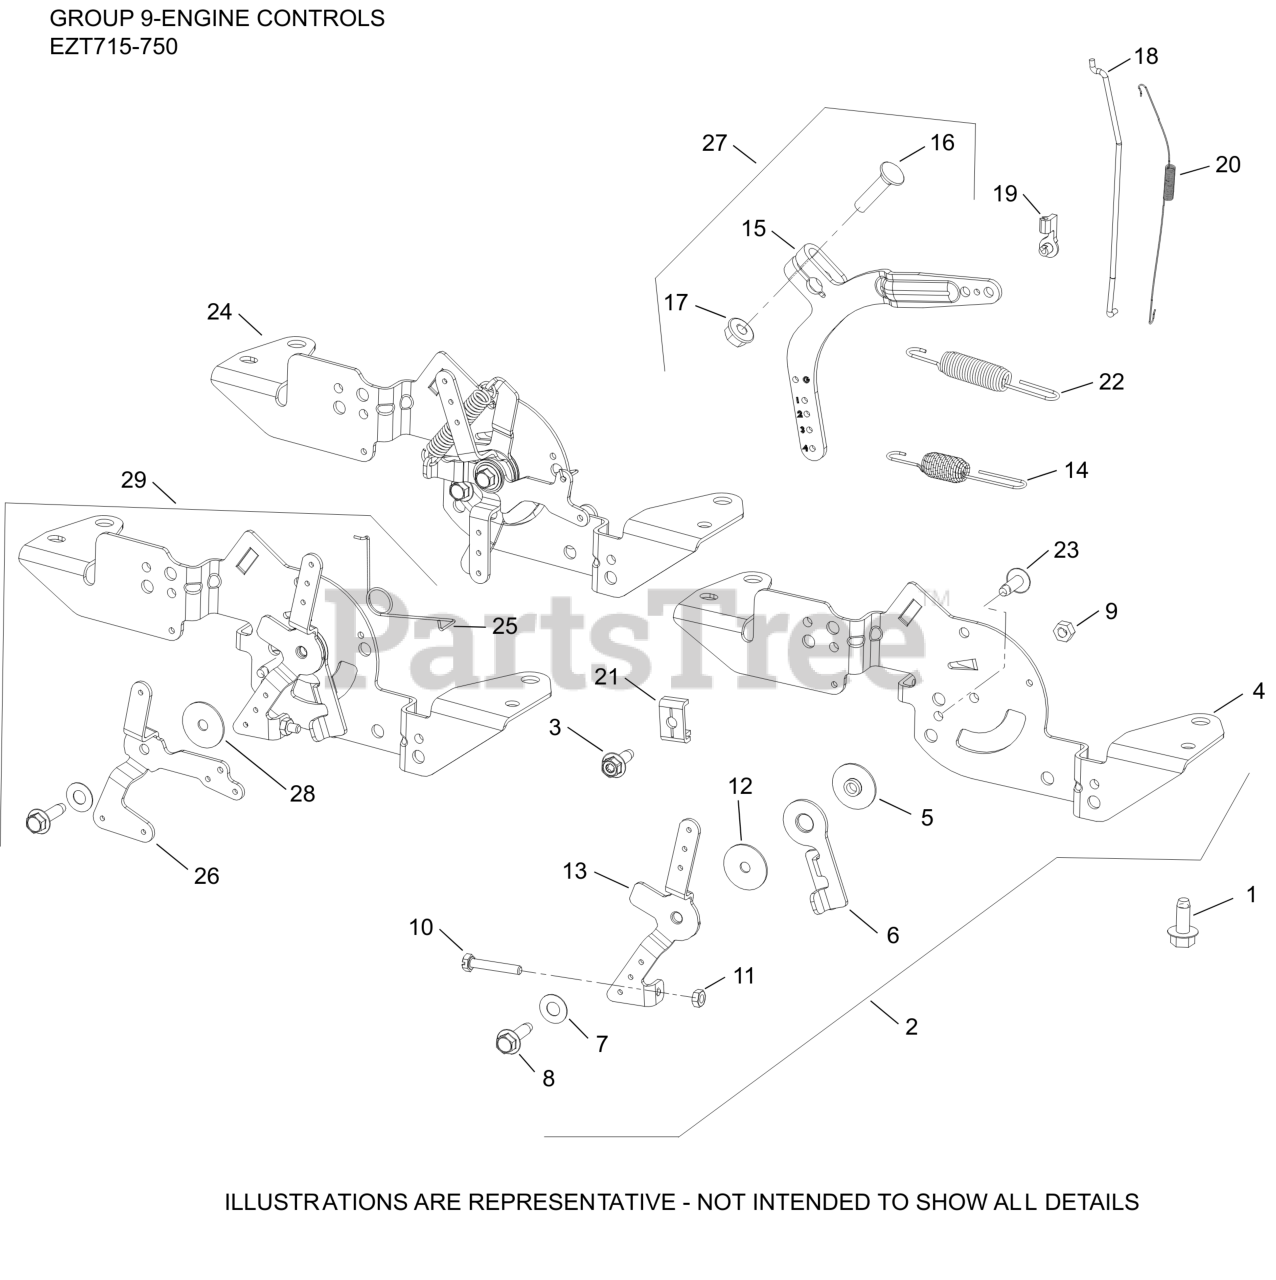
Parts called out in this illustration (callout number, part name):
1	SCREW, THREAD FORMING
3	SCREW, THREAD FORMING
4	BRACKET, SPEED CONTROL
5	SPACER, CONTROL ASSEMBLY
6	LEVER, THROTTLE ACTUATOR
7	WASHER, SPRING 1/4"
8	SCREW, THD FRM-USE 25 086 473-S
9	NUT, LOCK M5X.8
10	SCREW, SLT HD CAP M4X0.7X25
11	NUT, M4X0.7
12	WASHER, FLAT 5 MM
13	LEVER, THROTTLE CONTROL
15	LEVER, GOVERNOR - (#2409069S)
16	BOLT, RD HD SQ NECK M6X1.0X25
17	NUT, FLG M6X1.0
18	LINKAGE, THROTTLE
19	BUSHING, THROTTLE LINKAGE
20	SPRING, LINKAGE
21	CLAMP, CABLE CABLE
22	SPRING, GOVERNOR (CLEAR)
23	SCREW, THREAD FORMING
25	SPRING, CHOKE RETURN
26	LEVER, CHOKE
27	LEVER, GOVERNOR ASSEMBLY
28	WASHER, FLAT 5.5 MM
29	CONTROL ASSEMBLY, DUAL WIRE
